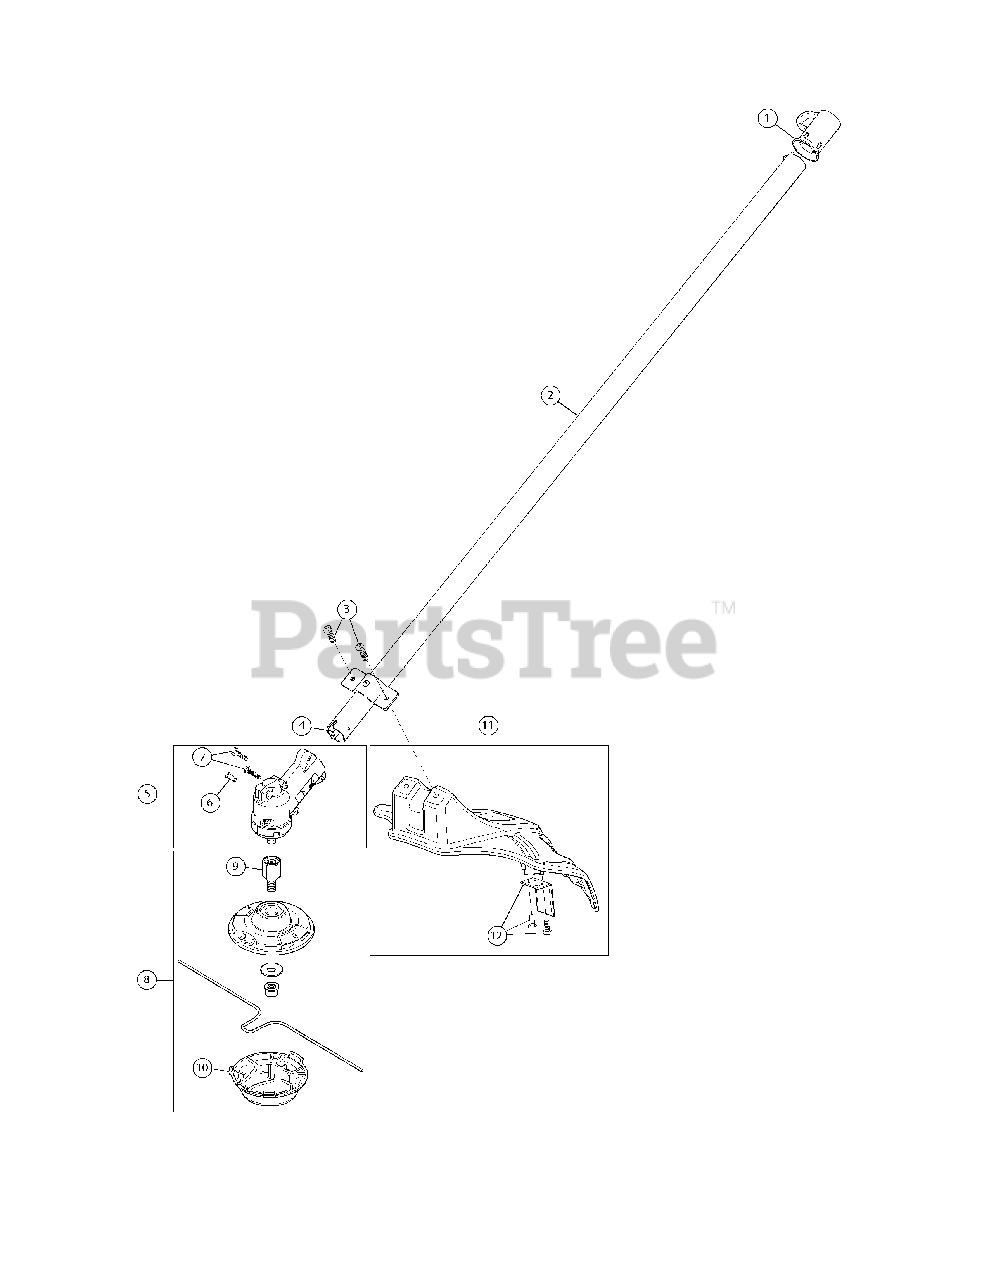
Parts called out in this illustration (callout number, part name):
2	Lower Drive Shaft Housing Assembly
3	Shield Mounting Screws
4	Lower Flexible Drive Shaft
5	Gear Box Assembly
6	Anti-Rotation Screw
7	Gearbox Mounting Hardware
8	Cutting Head Assembly
9	Shaft Extension
11	Shield Assembly
12	Blade Assembly
